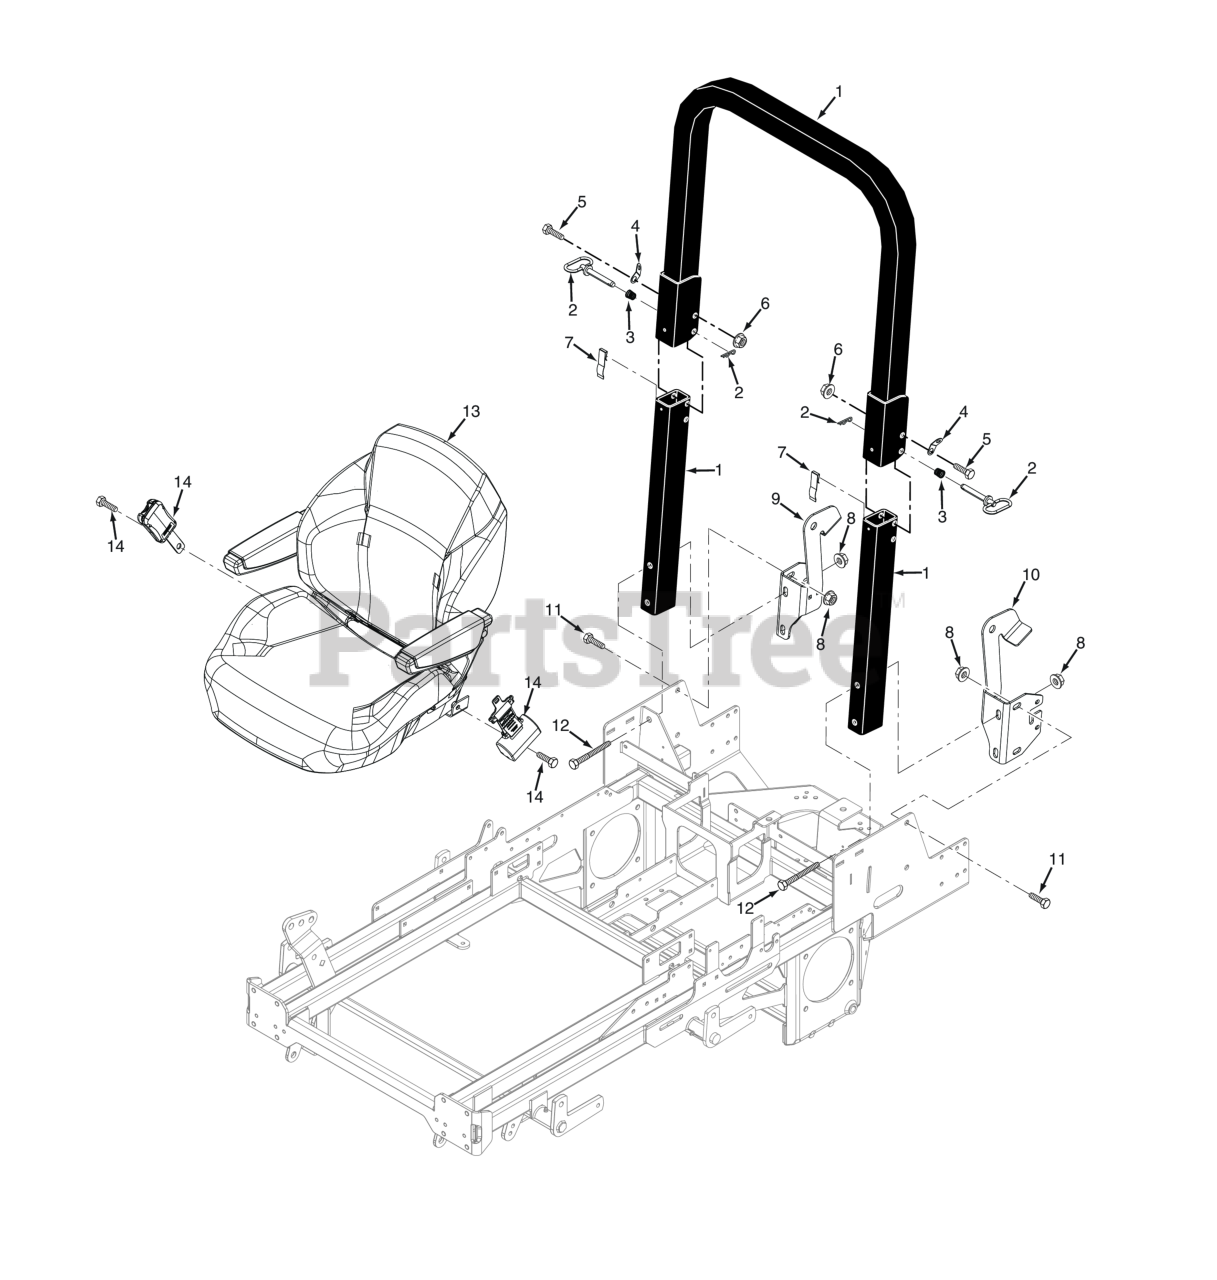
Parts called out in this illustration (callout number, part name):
1	ROPS, Foldable SCZ
2	Pin Assembly, ROPS Hinge
3	Spring, ROPS
4	Clip, ROPS
5	Bolt, Hex Head, 1/2-13 x 3-1/4"
6	HEX LOCKNUT, ELASTIC STOP, 1/2-13
7	Spring, ROPS Anti-Rattle
8	Nut, Elastic Stop 1/2-13, (STT-52 & STTII-52)
9	ROPS Mount, RH, 29CV-EFI
10	ROPS Mount, LH, 29CV-EFI
11	Bolt, Hex Head 1/2-13 x 1-1/4"
12	Bolt, Hex Head 1/2-13 x 4-1/4"
13	Seat Assembly (INCL 14)
14	Seat Belt Kit, Retractable - SCZII
